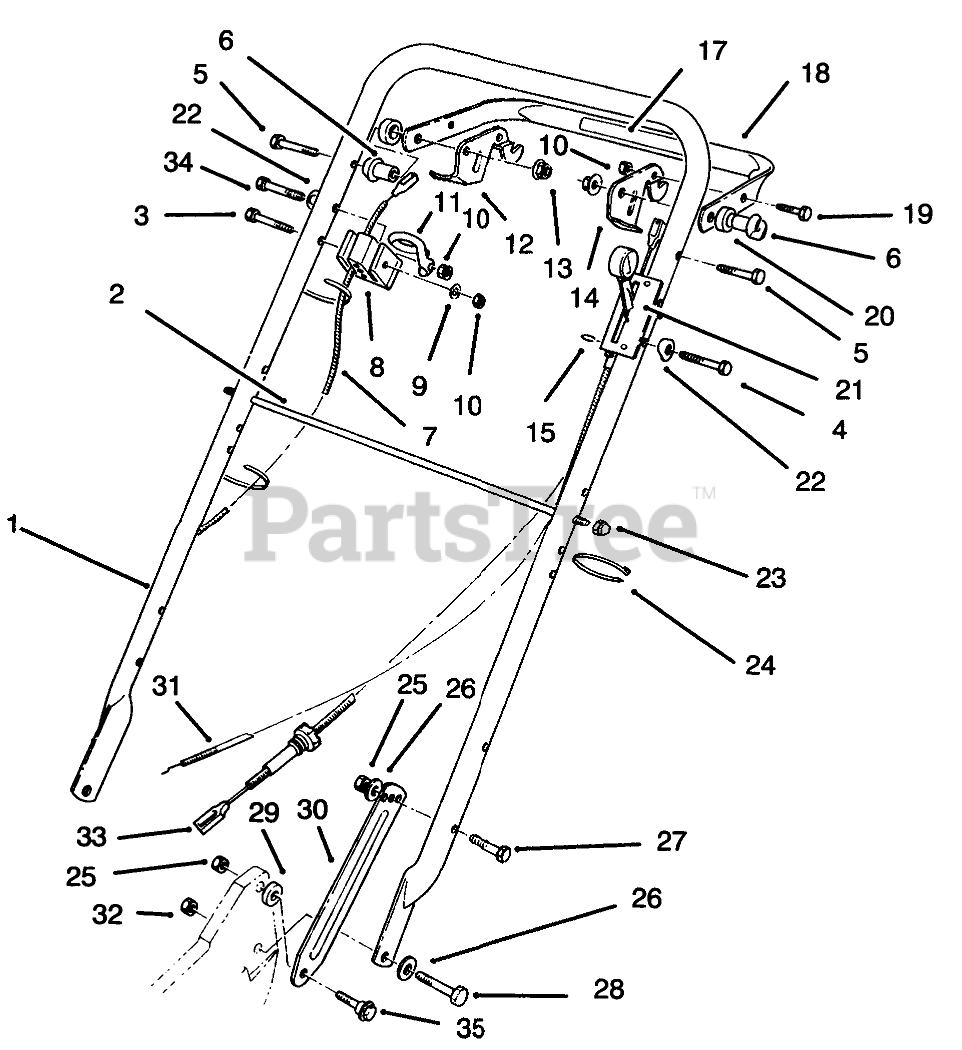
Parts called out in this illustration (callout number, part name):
1	Handle
2	ROD-SUPPORT, BAG
3	SCREW-HH
4	SCREW-HH
5	SCREW-HH
6	SPACER-SUPPORT
7	CABLE - BRAKE
8	SUPPORT-CABLE
9	WASHER-FLAT
10	NUT-LOCK, NI
11	GUIDE-ROPE
12	LEVER-CONTROL
13	NUT-LOCK, NI
14	LEVER-CONTROL
15	E-RING
17	DECAL/TRACTION CONTROL
18	Bar-Control
19	SCREW-HH
20	SPACER-NYLON
21	CONTROL-THROTTLE
22	WASHER
23	Nut-Acorn
24	TIE-CABLE
25	NUT-LOCK, NI
26	WASHER-BELLEVILLE
27	SCREW-HH
28	SCREW-HH
29	SPACER
30	Latch-Handle
31	CABLE - THROTTLE
32	NUT-LOCK, NI
33	CABLE-TRACTION
34	SCREW-HH
35	SCREW-SHOULDER
